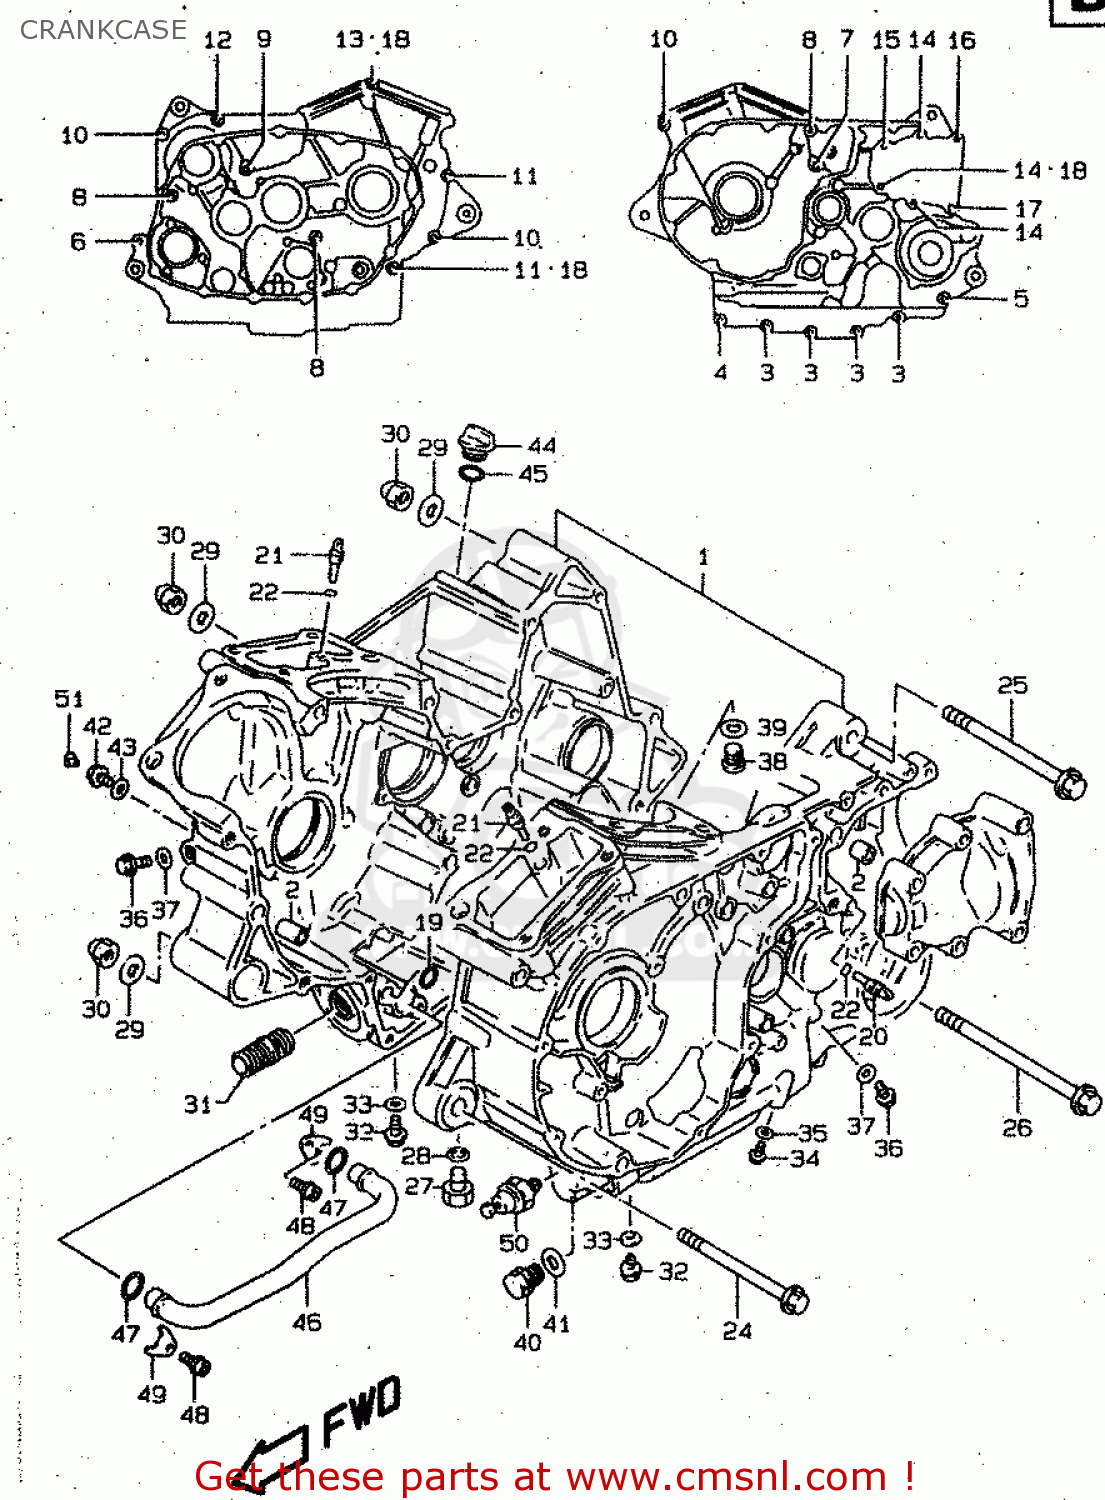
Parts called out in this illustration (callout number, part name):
1	CRANKCASE SET
2	PIN(8.4X11X20)
3	BOLT
4	BOLT
5	BOLT
6	BOLT
7	BOLT
8	BOLT
9	BOLT(8X120)
10	BOLT(8X95)
11	BOLT(8X105)
12	BOLT(8X120)
13	BOLT(8X160)
14	BOLT
15	BOLT
16	BOLT(8X55)
17	BOLT(8X65)
18	GASKET 8.2X14X1 (NAS)
19	O RING(D:1.9,ID:12.6)
20	JET,OIL GALLERY
21	JET,AIR(14)
22	O RING(D:1.2,ID:4)
23	WASHER(48.1X64X1.94)
24	BOLT(10X125)
25	BOLT(10X130)
26	BOLT(10X150)
27	BOLT
28	GASKET(12.1X16.2X3.7) (NAS)
29	WASHER
30	NUT
31	UNION,OIL STAND
32	BOLT
33	GASKET 8.2X14X1 (NAS)
34	PLUG(10X12)
35	GASKET(10X14X3.6) (NAS)
36	BOLT
37	GASKET(5.8X11X1.2) (NAS)
38	PLUG
39	GASKET(16X22X2) (NAS)
40	PLUG(14X12)
41	GASKET(13.8X18.8X4.8) (NAS)
42	BOLT
43	GASKET 8.2X14X1 (NAS)
44	PLUG
45	O RING(D:3.1,ID:16.8)
46	PIPE,OIL GALLERY
47	O RING(D:3.1,ID:14.8)
48	BOLT
49	CLAMP,OIL PIPE
50	SWITCH ASSEMBLY,OIL PRESSURE
51	CAP(OD:11)
